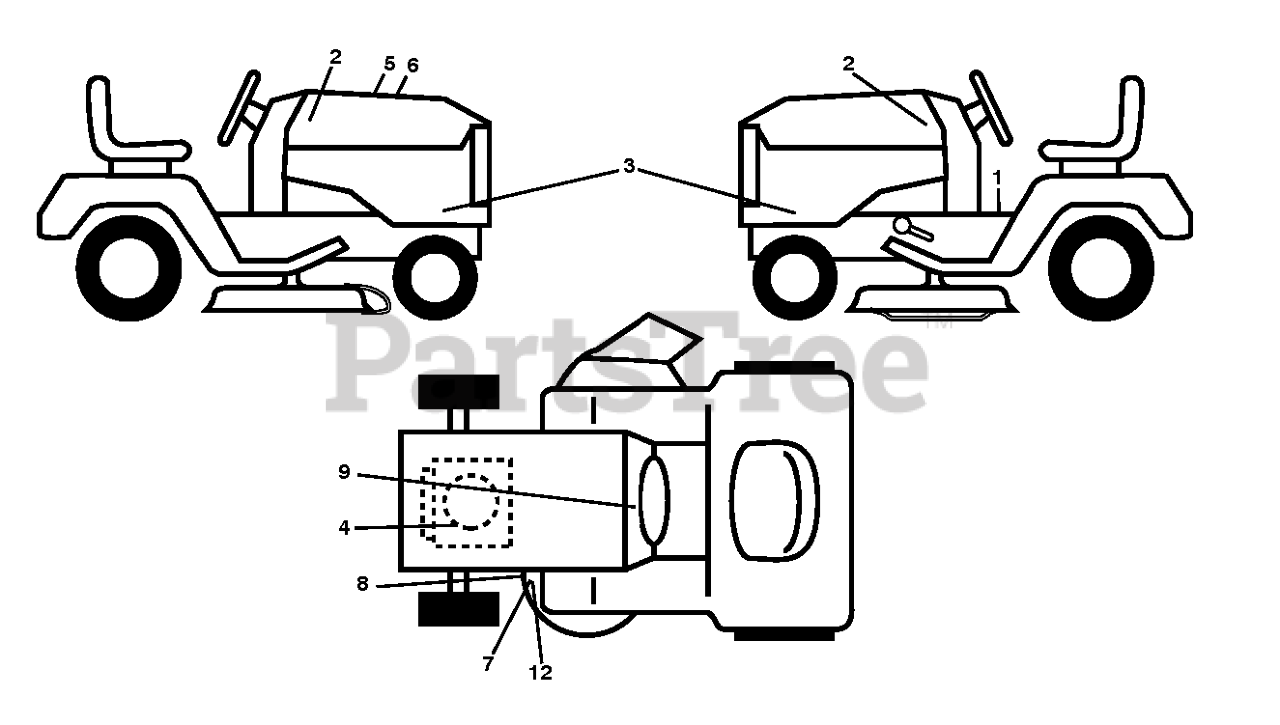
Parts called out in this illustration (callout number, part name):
1	DECAL.FENDER.WARNING
2	DECAL.BADGE.170MM.TEXTLOGO.
3	DECAL.SDPNL.YTH26V54.2011.HUSQ
4	DECAL.ENG.BS.26 HP.PROF.278955
5	DECAL.WARNING.CUST.RESP.E85.
6	DECAL.RPL.BSM44.PROF.TLW.54K46
7	DECAL.WARN.KEEP.HAND.AWAY
8	DECAL.MOWER
9	DECAL BTRY SYMBOLS
12	DECAL.MOWER.SCH.48/54
